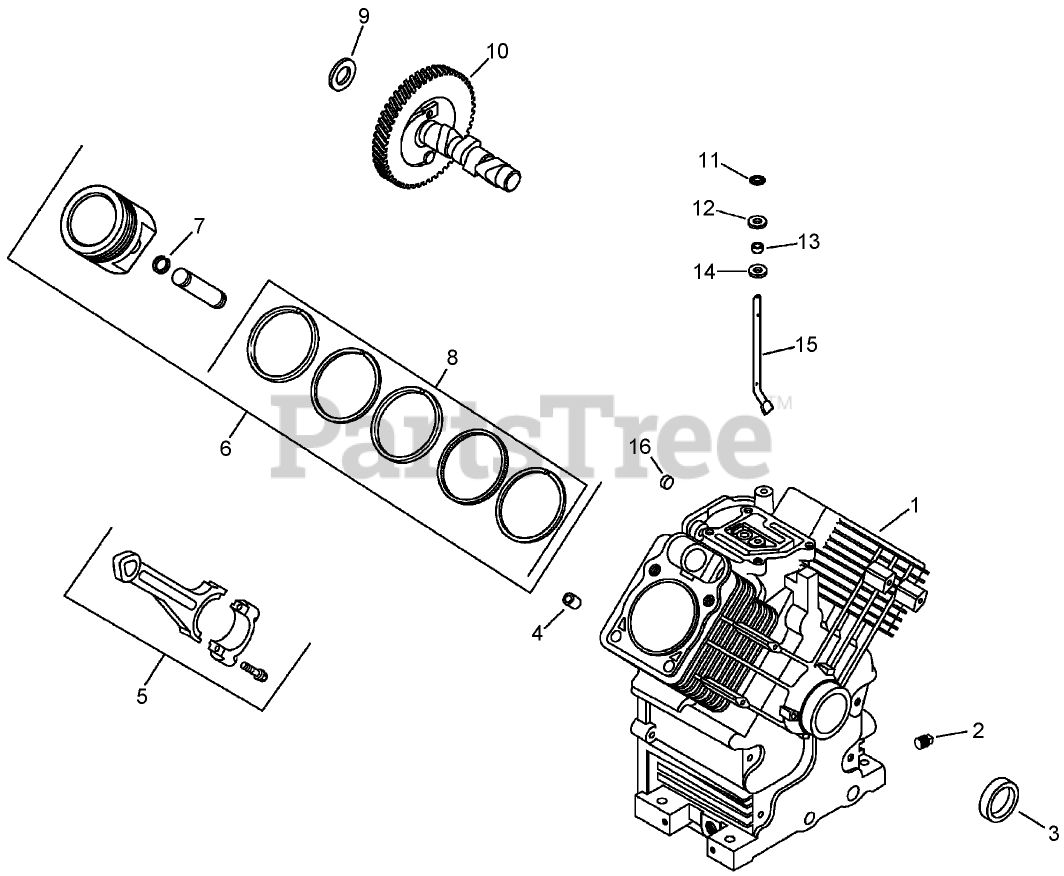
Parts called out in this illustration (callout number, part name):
1	Crankcase (Use Short Block or Miniblock)
2	PLUG-PIPE, SQ HD (3/8)
3	SEAL-OIL
4	Pin-Locating
5	Rod-Connecting (Standard)
5	Rod-Connecting (.25)
6	Piston w/Ring Set (Std.) (Includes 7, 8)
6	Piston w/Ring Set (.08)
6	Piston w/Ring Set (.25)
6	Piston w/Ring Set (.50)
7	RETAINER-PIN, PISTON
8	Ring Set (STD and .08)
8	Ring Set (.25)
8	Ring Set (.50)
9	SHIM-CAMSHAFT (RED .032)
9	SHIM-CAMSHAFT (BLACK .04)
9	SHIM-CAMSHAFT (WHITE .028)
9	SHIM-CAMSHAFT (BLUE .03)
9	SHIM-CAMSHAFT (YELLOW .034)
9	SHIM-CAMSHAFT (GREEN .036)
9	SHIM-CAMSHAFT (GRAY .038)
10	Camshaft Kit
11	RETAINER-RING
12	WASHER-FLAT (9MM)
13	SEAL-CROSS SHAFT, GOVERNOR
14	WASHER-FLAT (11/32)
15	SHAFT-CROSS, GOVERNOR
16	PLUG-CUP
